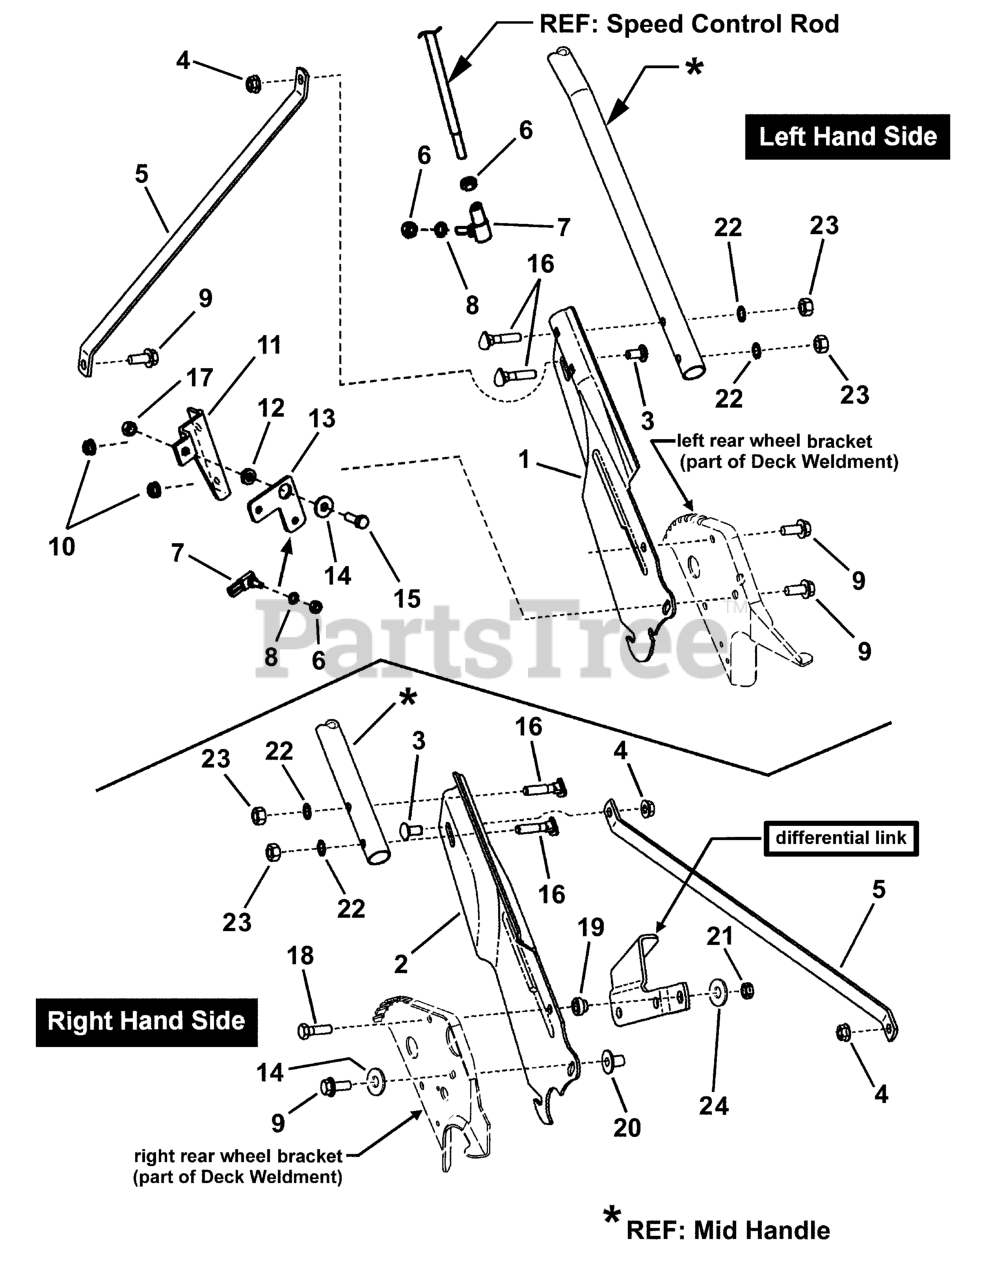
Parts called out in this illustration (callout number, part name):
1	HANDLE, Lower LH (Adjustable)
2	HANDLE, Lower RH (Adjustable)
3	BOLT, 5/16-18 x 5/8" Short Neck Carriage GR 5
4	NUT, 5/16-18 Hex Flange Lock GR 5
5	BRACE, Handle
6	HN, 1/4F GR5 YZ
7	BALL JOINT, 1/4-28
8	WASHER, 1/4" Internal Tooth Lock
9	BOLT, 5/16-18 x 3/4" Hex Flange Lock GR 5
10	NUT, 5/16-18 Hex Flange Lock, GR 5
11	BRACKET, Bell Crank
12	SPACER, .33 x .63 x .156
13	BELL CRANK
14	WASHER, .33 x .88 x .09 Flat
15	SCREW, 5/16-18 x 7/8" Hex Head Cap, GR 5
16	BOLT, 5/16-18 x 1-1/2" Curved Head
17	NUT, 5/16-18 Hex Center Lock
18	SCREW, 5/16-24 x 1" Hex Head Cap GR5
19	BUSHING, Differential
20	TEE-NUT, 5/16-18
21	NUT, 5/16-24 Hex Center Lock, GR 5
22	WASHER, 5/16" Internal Tooth Lock
23	NUT, 5/16-18 Hex, GR 5
24	WASHER, 3/8" Flat
